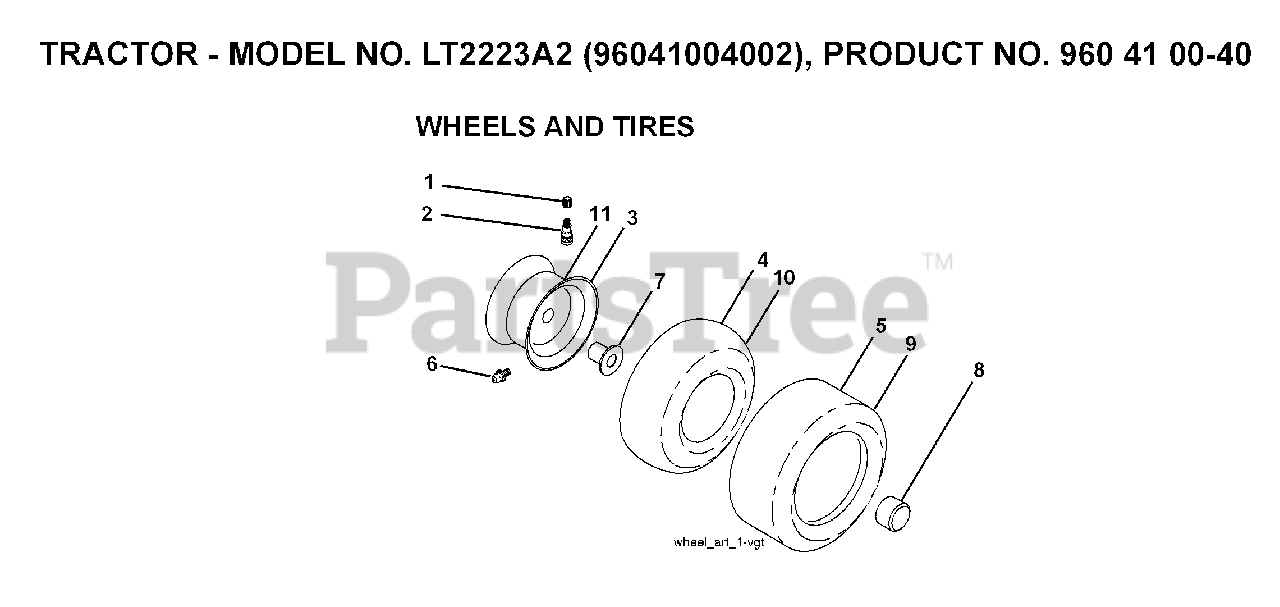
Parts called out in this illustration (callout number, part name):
1	VALVE CAP
2	VALVE STEM LT
3	RIM ASSEMBLY, FRONT
4	TUBE.16X6.5/7.5-8
5	TIRE HEAVY DUTY
6	FITTING LT
7	BEARING T
8	CAP, AXLE BLK
9	TIRE.R.TS.22 (22X9.50-12)
10	TUBE 23X950X12
11	RIM.ASM.12"REAR.SVC.417
